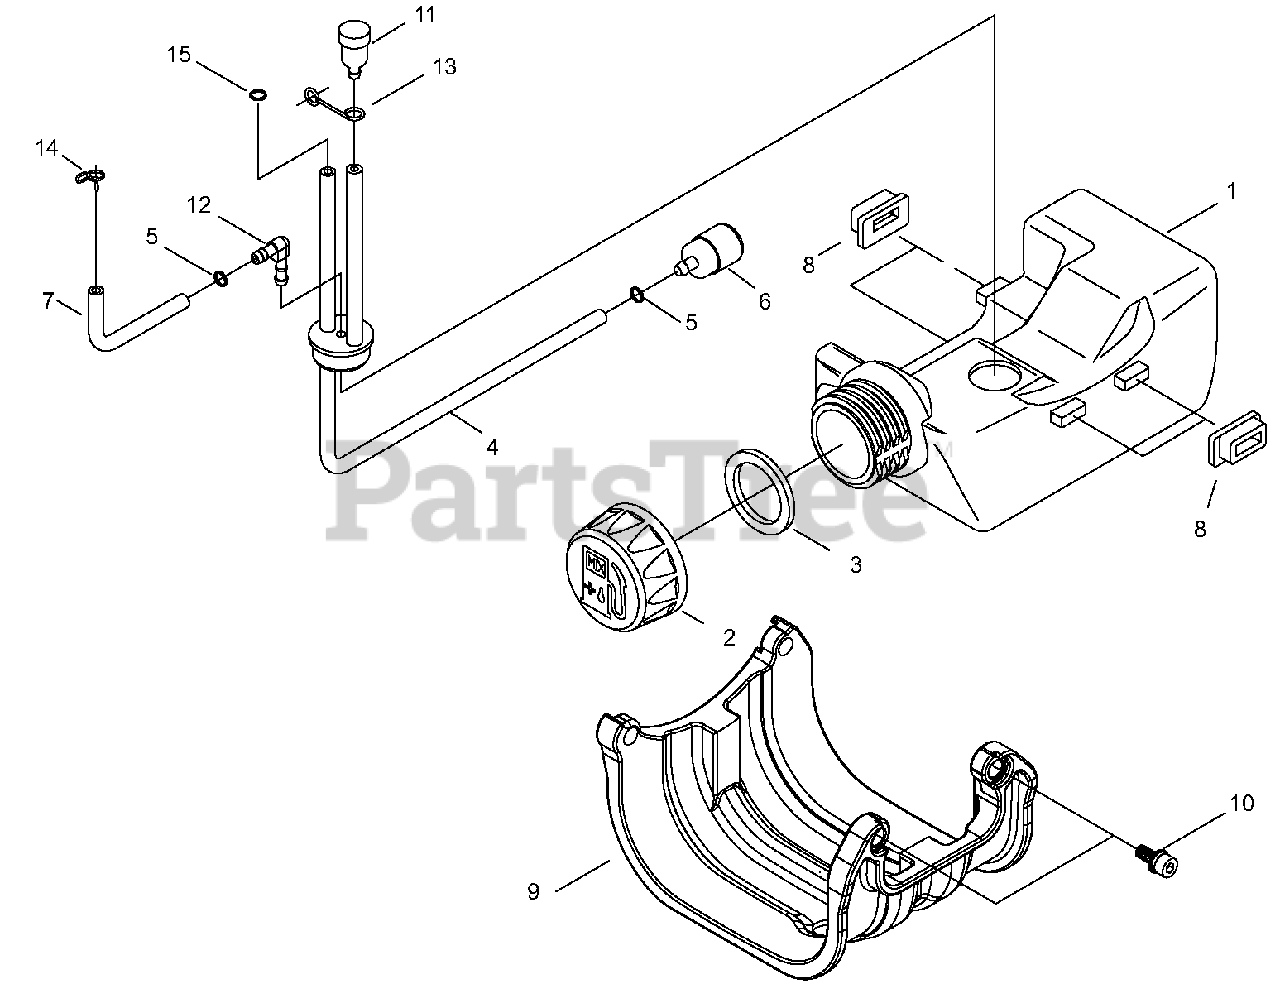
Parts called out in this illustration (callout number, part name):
1	TANK, FUEL
2	CAP, FUEL
3	GASKET, FUEL CAP
4	PIPE, FUEL
5	CLIP Ø6
6	FILTER, FUEL 125-528
7	PIPE, FUEL RETURN
8	CUSHION, FUEL TANK
9	GUARD, PLASTIC FUEL TANK
10	BOLT M5×16
11	VENT ASSY
12	CONNECTOR, PIPE
13	CLIP, VENT ASSY
14	CLIP, SPRING Ø5.2
15	CLIP Ø6
